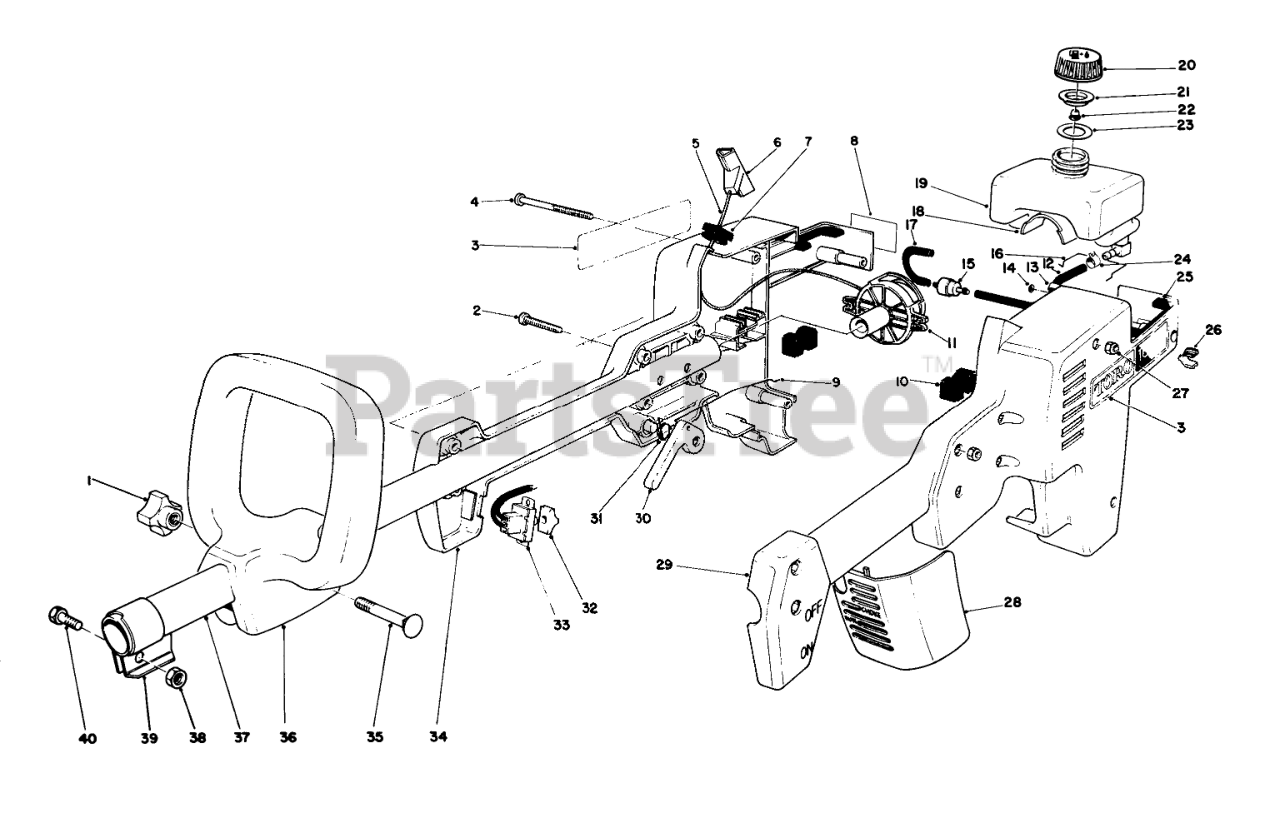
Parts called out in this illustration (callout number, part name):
1	Knob
2	Screw-Machine Cross Recess Pan Hd.
3	Decal-Toro TC350
4	Screw-Machine Cross Recess Pan Hd.
5	Rope-Starter
6	Handle
7	Bushing Rope
8	Decal-Hot
9	Link-Throttle
10	Isolation Mount
11	Recoil Assembly (Incl. Ref. #5, 6 & 7)
12	Gas Line
13	Clamp Cable
14	Retainer-Push On
15	FUEL FILTER
16	Clip-Crankcase Pad
17	Gas Line
18	Crankcase Pad
19	GAS TANK
20	Gas Cap Assembly (Incl. Ref. #21-23)
21	Insert-Gas Cap
22	Valve-Umbrella/Check
23	Gasket
24	CLAMP-HOSE
25	Bumper-Gas Tank
26	Grommet
27	NUT-LOCK, NI
28	Cover-Air Cleaner
29	Housing Engine L.H.
30	Lever Throttle
31	TORSION SPRING
32	SWITCH COVER-BLACK
33	SWITCH
34	Housing-Engine R.H.
35	BOLT-CARRIAGE
36	HANDLE SECONDARY
37	Tube-Upper Shaft Housing
38	NUT-LOCK, NI
39	Clamp-Pole
40	SCREW-HH
